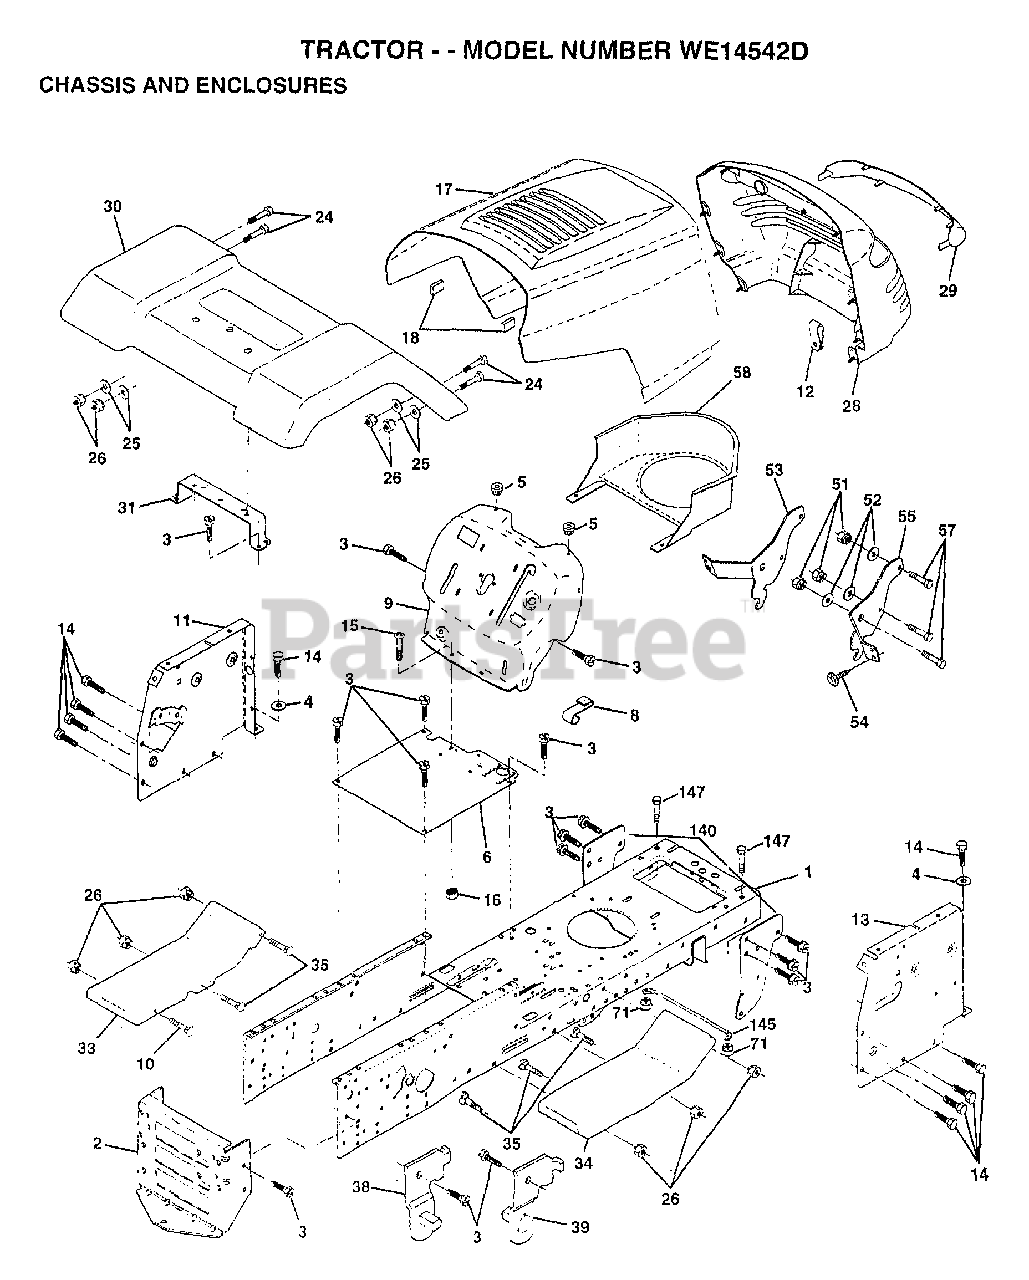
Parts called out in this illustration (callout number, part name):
1	CHASSIS ASM
3	SCREW
4	WASHER
5	BUMPER-HOOD/DASH
6	SADDLE
8	CLIP.RETAINER
9	DASH.SILKSCREENED
11	"PANEL-DASH,LH"
12	CLIP.TINNERMAN
14	SCREW LT
15	SCREW
24	BOLT
25	WASHER
26	NUT
28	GRILLE-MS428
29	LENS GRILLE
31	BRKT FENDER
33	FOOTREST.LH.PERF.
34	FOOTREST.RH.PERF.
35	BOLT
38	BRACKET ASM LH
39	BRACKET ASM RH
51	NUT
52	WASHER
53	BRACKET.GRILLE.LH
55	BRACKET.GRILLE.RH
58	AIR DUCT
140	BRKT SUSPENSION
145	"ROD POVOT,CHASSIS"
147	BOLT LT
